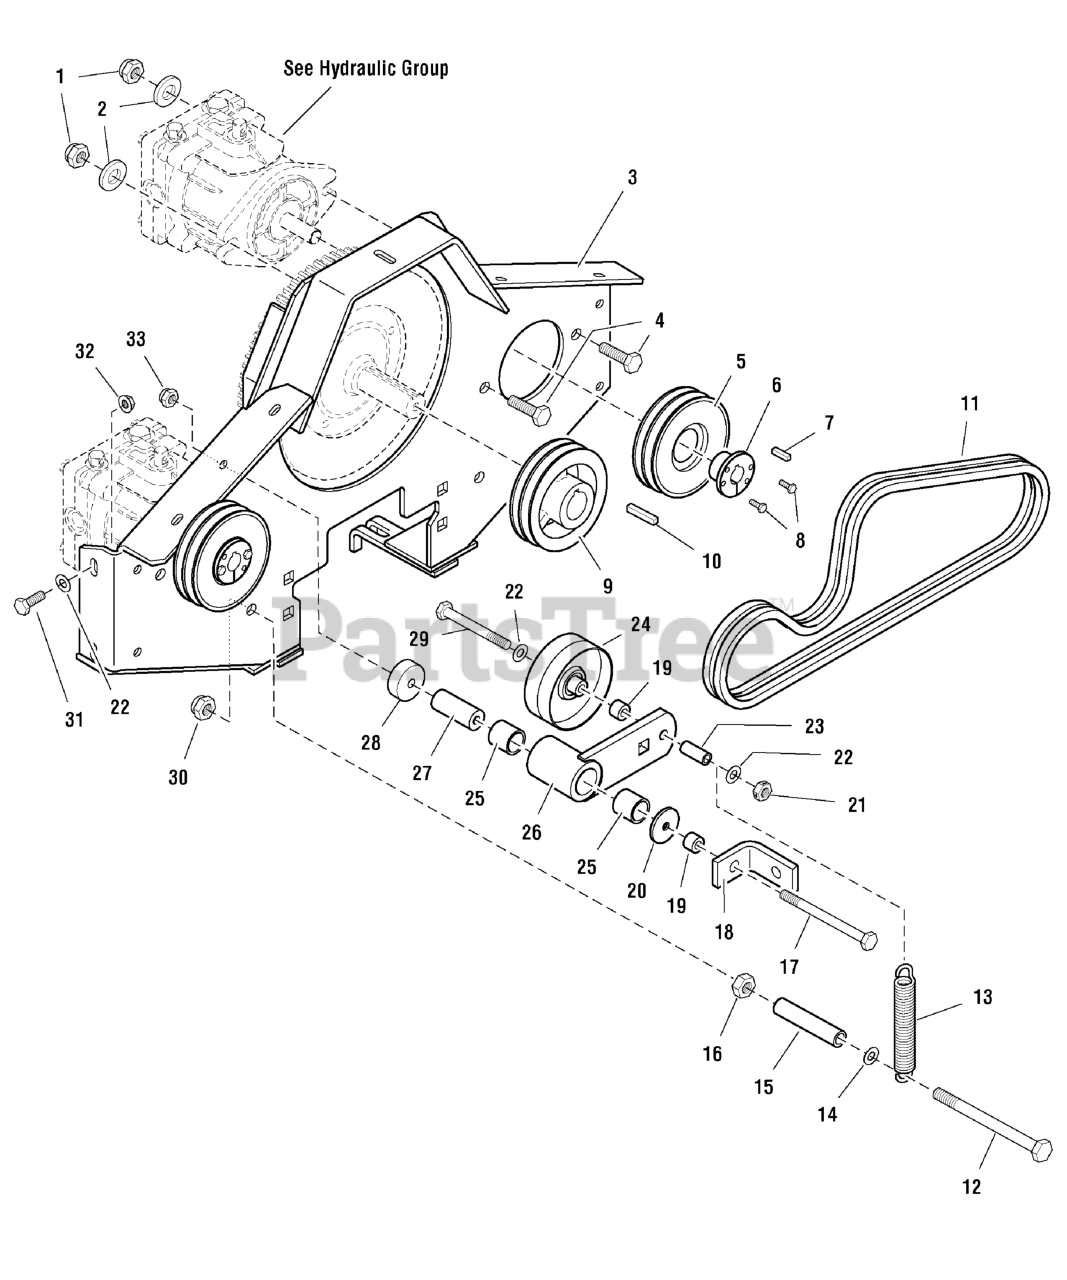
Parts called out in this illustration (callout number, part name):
1	NUT, Hex, Nylon Lock, 1/2-20
2	WASHER, Frame Retaining
3	PUMP MOUNT PLATE
4	BOLT, 1/2-20 X 1-3/4" GD8 CZ
5	PULLEY, Pump Drive
6	HUB, Taper Lock
7	KEY, 5MM SQ. x 25MM w/ Round Ends
8	BOLT, 1/4-20 X 1" GD5 CZ
9	PULLEY, 5.75" OD X 1.375" BORE, DOUBLE A
10	KEY, 5/16" SQ RD ENDS, 1.46 LG
11	BELT, Pump Drive (set of 2)
12	BOLT, 1/2-13 x 5
13	SPRING, Extension, Swivel End
14	WASHER, 1/2 SAE
15	HOSE, 3-1/4
16	NUT, 1/2-13 Hex Jam
17	BOLT, 3/8-16 X 4-1/2" GD5 CZ
18	SPRING ANCHOR
19	SPACER, .39 x .75 x .38
20	WASHER, 3/8 x 1-3/4
21	NUT, 3/8-16 Hex Side Lock
22	WASHER, 3/8 SAE
23	SPACER, .38 x .50 x .75
24	PULLEY, Idler, Flat
25	BUSHING, Brass
26	PUMP DRIVE IDLER ARM
27	SPACER, .39 X 1.00 X 2.55, SS
28	SPACER, .45 x 1.88 x .38
29	BOLT, 3/8-16 X 3" GD5 CZ
30	NUT, 1/2-13 HEX NYLON LOCK
31	BOLT, 3/8-16 X 1" GD5 CZ
32	NUT, 3/8-16 Hex Serrated Flange
33	NUT, 3/8-16 HEX NYLON LOCK
